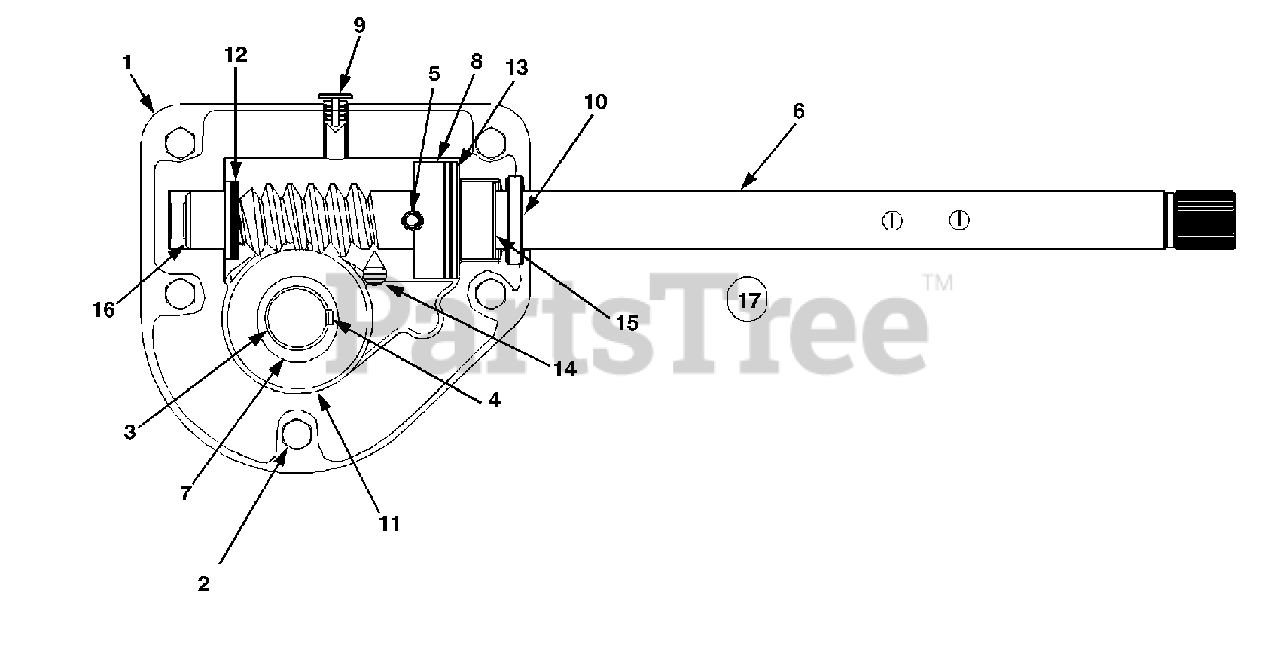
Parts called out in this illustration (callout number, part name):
1	Housing-R.H.
2	Hex Screw 1/4-20 x .75
3	Spiral Axle
4	Key
5	Pin-Spiral
6	Shaft-Worm
7	Gear-Worm
8	Collar-Thrust
10	Seal-Oil
11	Washer-Flat
12	Washer-Flat
13	Washer-Flat
14	Grease
15	Bearing-Flange
16	Bearing-Flange
17	Assembly, Complete 24"
